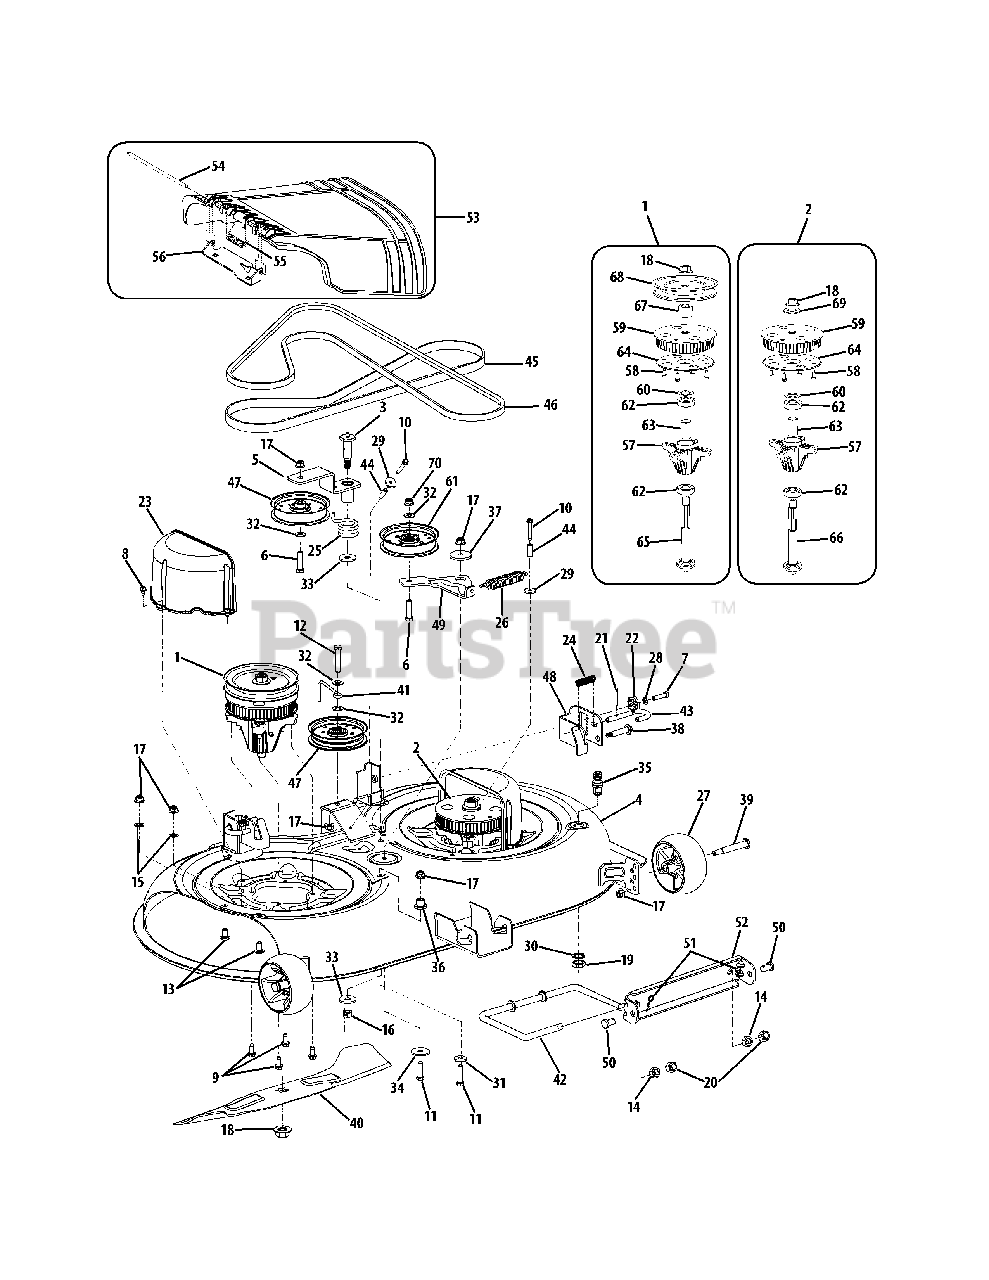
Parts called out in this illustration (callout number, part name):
1	Spindle Assembly - Drive
2	Spindle Assembly - Driven
3	Shoulder Bolt
5	Idler Bracket
6	Hex Screw, 3/16-18 x 1.5
7	Hex Screw, 5/16-18 x 1.25
8	Hex Washer Screw, 1/4-20 x .5
9	Hex Washer Screw, 5/16-18 x .750
10	Hex Washer Screw, 1/4-20 x 1.625
11	Hex Screw, 3/8-16 x 1.25
12	Hex Screw, 3/8-16 x 2.0
13	Carriage Screw, 3/8-16 x .75
14	Hex Nut, 1/2-13
15	Push Nut, 3/8
16	Hex Lock Nut, 7/16-14
17	Hex Flange Lock Nut, 3/8-16
18	Hex Flange Nut, 5/8-18
19	Hex Nut, M16-1.5
20	Hex Lock Nut, 1/2-13
21	Cotter Pin, 1/8 x 1.25
22	Deck Adjust Gear
24	Compression Spring, .535 x 1.751
25	Torsion Spring, 1.10 x 1.3
26	Extension Spring, .865 x 4.68
27	Deck Wheel, 5.0
28	Lock Washer, 5/16
29	Flat Washer, .265 x .938 x .12
30	Internal Tooth Lock Washer, 5/8
31	Flat Washer, .385 x 1.0 x .135
32	Flat Washer, .406 x .875 x .059
33	Flat Washer, .450 x 1.250 x .164
34	Flat Washer, .406 x 1.5 x .105
35	Deck Wash Nozzle
36	Shoulder Spacer, 1.38 x .445 x .36
37	Shoulder Spacer, .884 x .190
38	Shoulder Bolt, 5/16 -24 x .435 x 1.76
39	Shoulder Bolt, 3/8-16 x .496 x 2.5
40	2-in-1 Blade
41	Belt Keeper Rod
42	Deck Front Hanger Rod
43	Deck Release Rod
44	Spacer, .26 x .372 x 1.03
45	Timing Belt
47	Idler Pulley, 4.25
48	Deck Hanger/Adjust LH Bracket
51	Internal Cotter Pin
52	Front Deck Rod Bracket
53	Chute Deflector Assembly
55	Torsion Spring, .44 x 2.0
56	Chute Mounting Bracket
57	Spindle Housing
58	Screw, 1/4-10 x .625
59	Timing Pulley
60	Flat Washer, .793 x 1.24 x .06
61	Idler Pulley
62	Ball Bearing
63	Spacer, .792 x 1.06 x 1.86
64	Timing Pulley Plate
65	Spindle Shaft
66	Spindle Shaft
67	Spacer, .735 x 1.375 x1.066
68	Deck Pulley
69	Flat Washer, .76 x 1.5 x .12
70	Jam Lock Nut, 3/8-16
